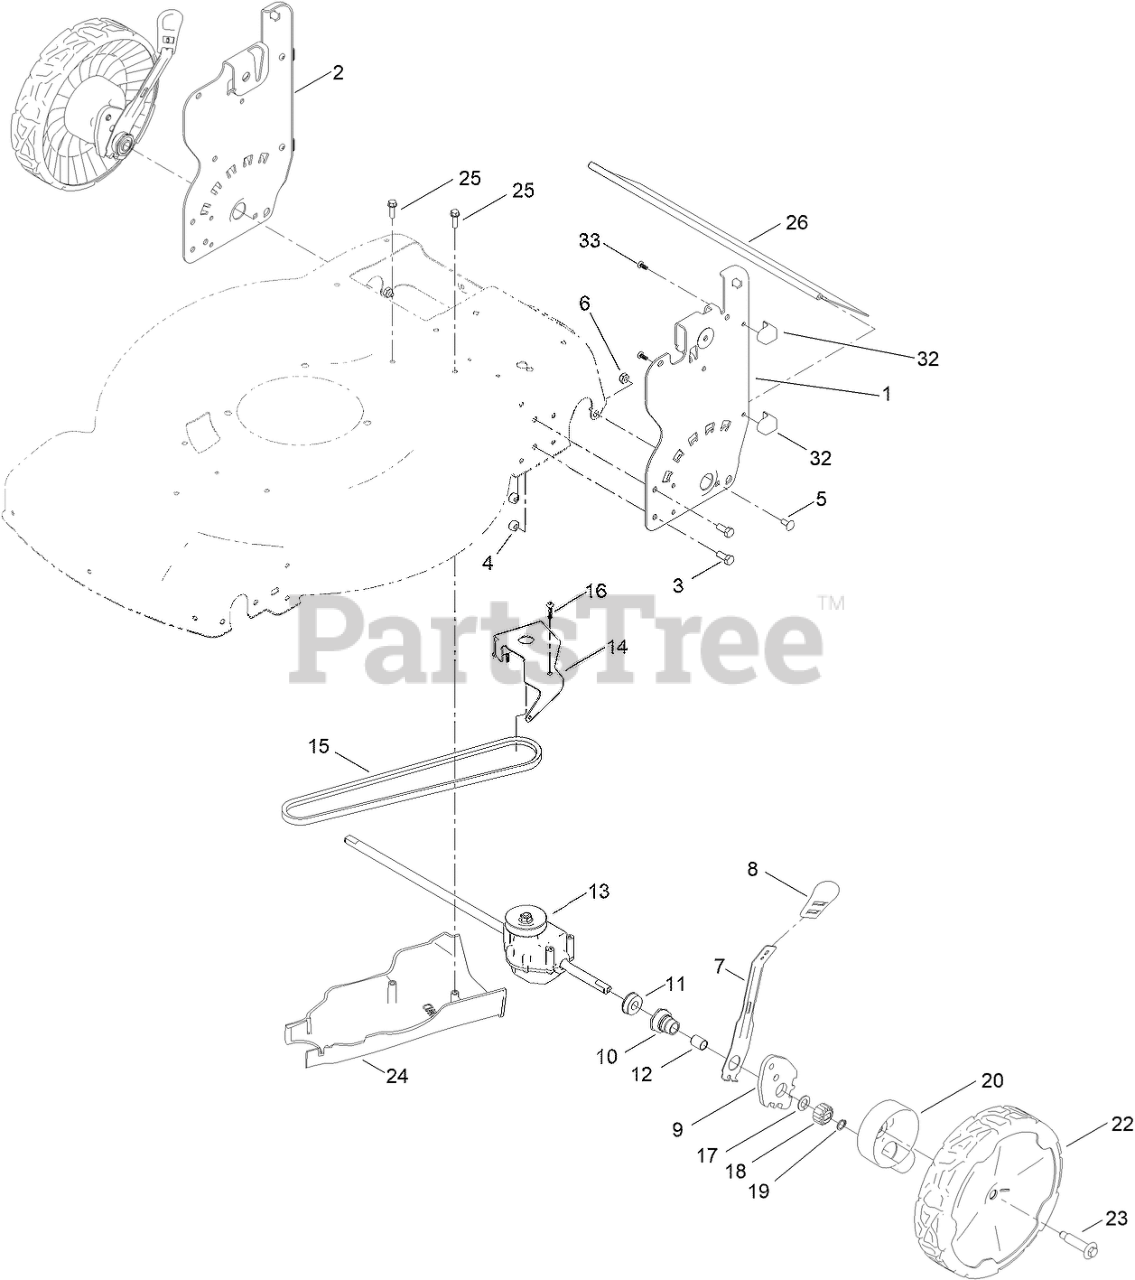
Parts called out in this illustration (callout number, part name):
1	PLATE-HOC, LH (2 HOLE)
2	PLATE-HOC, RH (2 HOLE)
3	SCREW-HH
4	NUT-LOCK, NI
5	SCREW-CARR
6	NUT-LOCK, NI
7	ARM-SPRING
8	KNOB-HOC
9	ARM-PIVOT, REAR
10	RETAINER-BUSHING, HOC
11	BEARING-BALL
12	BUSHING-SLEEVE
13	TRANSMISSION-RWD
14	BRACKET-TRANSMISSION
15	V-BELT
16	SCREW-PLASTITE
17	WASHER-THRUST
18	GEAR-PINION, 15T
19	RING-RETAINING
20	ASM-COVER, GEAR (DK GRAY)
22	ASM-9.65" WHEEL, GEARED
23	WHEEL BOLT
24	COVER-BELT, RWD
25	SCREW-HWH
26	SHIELD-TRAILING
32	PAD-SMART STOW
33	SCREW-PLASTITE
